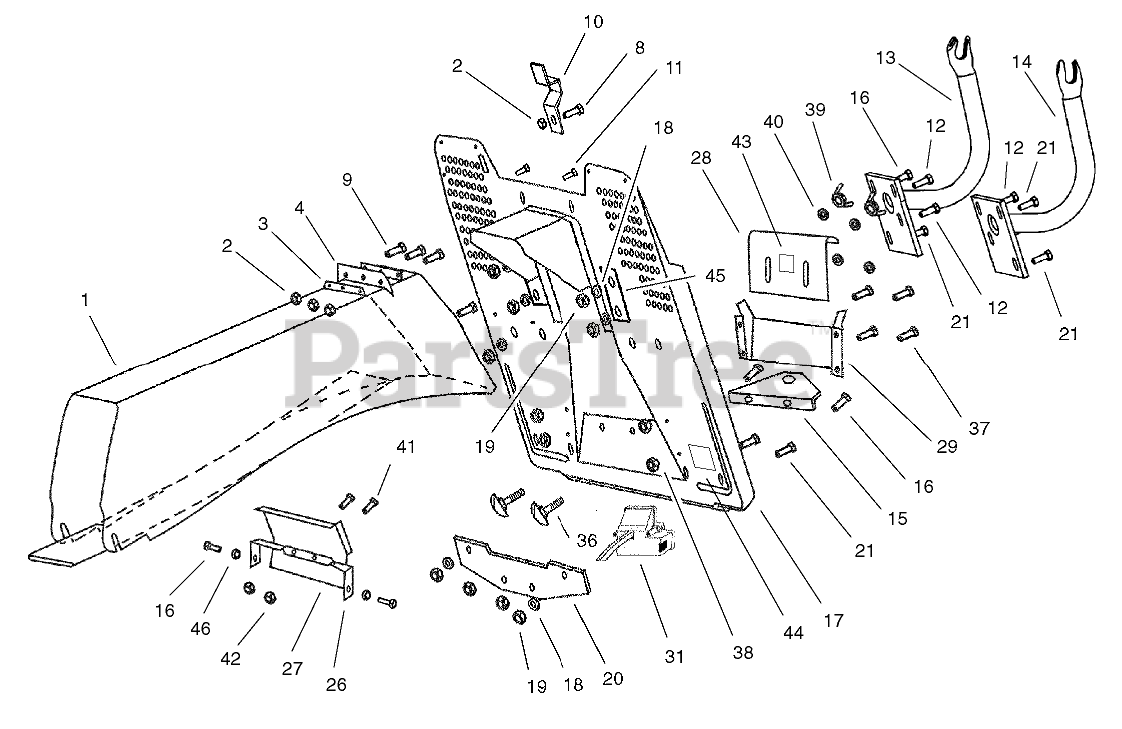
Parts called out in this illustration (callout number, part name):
1	TUNNEL
2	NUT-HEX
3	PLATE-SUPPORT
4	SEAL-RUBBER
9	SCREW-SFH
10	COVER-SWITCH
11	BOLT-CARRIAGE
13	SUPPORT-COLLECTOR, RIGHT
14	SUPPORT-COLLECTOR, LEFT
15	HITCH-TOW
16	SCREW-HEX
17	COLLECTOR PLATE ASM
18	WASHER-FLAT
19	NUT-LOCK, NI
20	SUPPORT-HITCH, TOW
21	SCREW-HEX
26	BRACKET-SHIELD, PROTECTIVE
27	SHIELD-PROTECTIVE
28	Shield-Adjustable
29	Hopper-Receiving
31	OVERLOAD SWITCH ASM
36	BOLT-CARR
37	SCREW-HH
38	NUT-LOCK
39	NUT-WING
40	WASHER-FLAT
41	BOLT-CARRIAGE
42	NUT-LOCK
43	DECAL-POSITION, BAGGING
44	DECAL-BYPASS, HYDRO
45	Plate-Reinforcing
46	Washer-Spring
